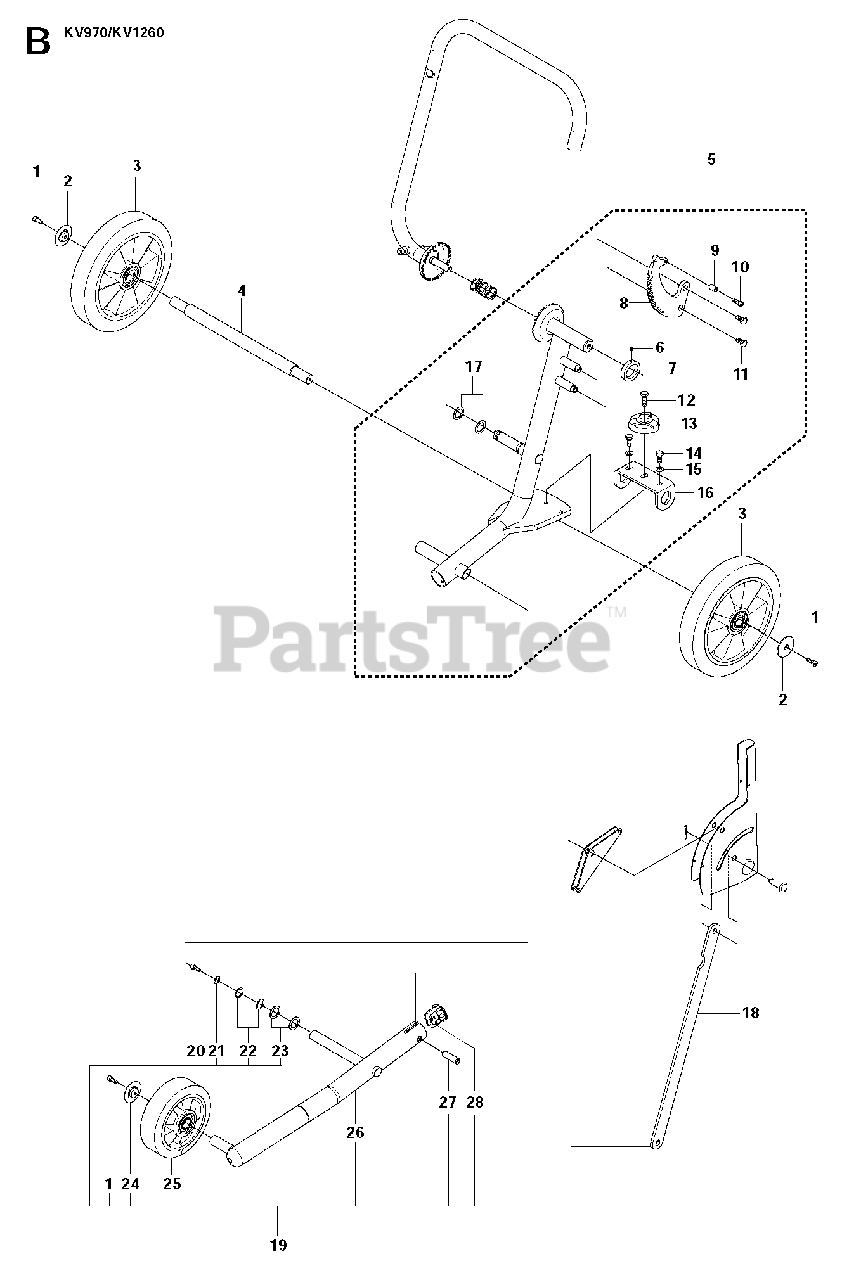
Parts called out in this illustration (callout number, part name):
10	SCREW IHSCM
11	SCREW EHHM
13	TURNING KNOB
19	FRAMEIncl. 1, 20 - 28
20	SCREW EHHM
